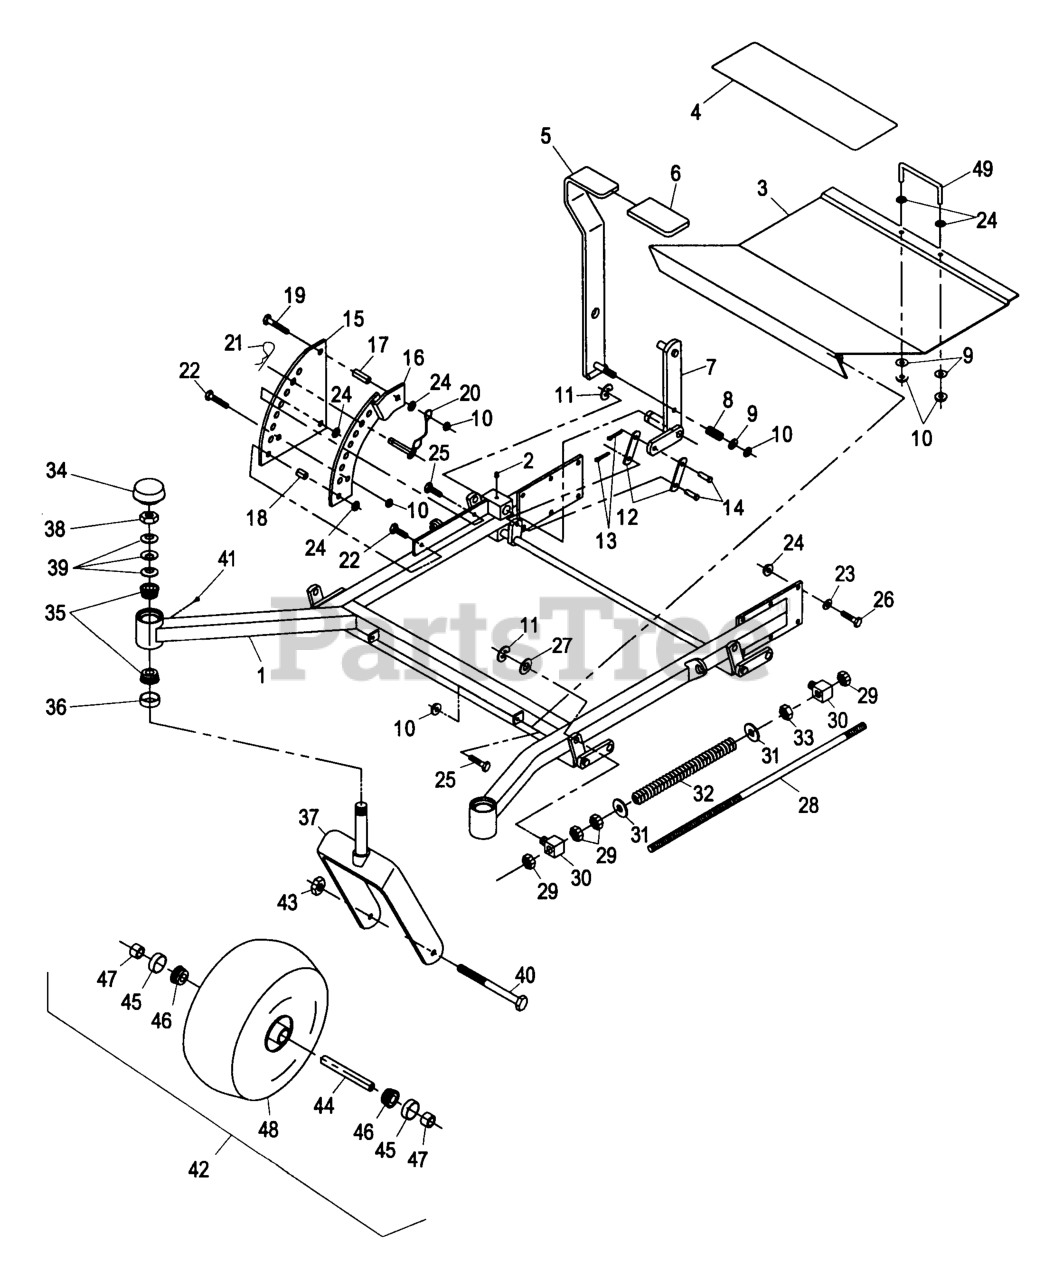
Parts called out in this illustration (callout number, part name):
4	PAD-ANTISKID
6	GRIP-LEVER, LIFT
8	SPRING-COMPRESSION
12	ARM-LIFT, DECK
14	PIN-CLEVIS
17	BUSHING-LEVER, LIFT
18	BUSHING-LEVER, LIFT
20	PIN-HITCH (W/LANYARD)
21	PIN-COTTER
28	ROD-LIFT, DECK
30	SWIVEL-DECK MOUNT, REAR
32	SPRING-SUPPORT, DECK
34	CAP-GREASE
35	Cone-Bearing Tapered Roller
36	SEAL-GREASE
39	WASHER-BELLVILLE
44	SPACER-CASTER, FRONT
45	SEAL-BEARING
46	BEARING-CONE, TAPERED ROLLER
47	SPACER-BEARING
48	WHEEL AND TIRE ASM
49	HANDLE,DECK
